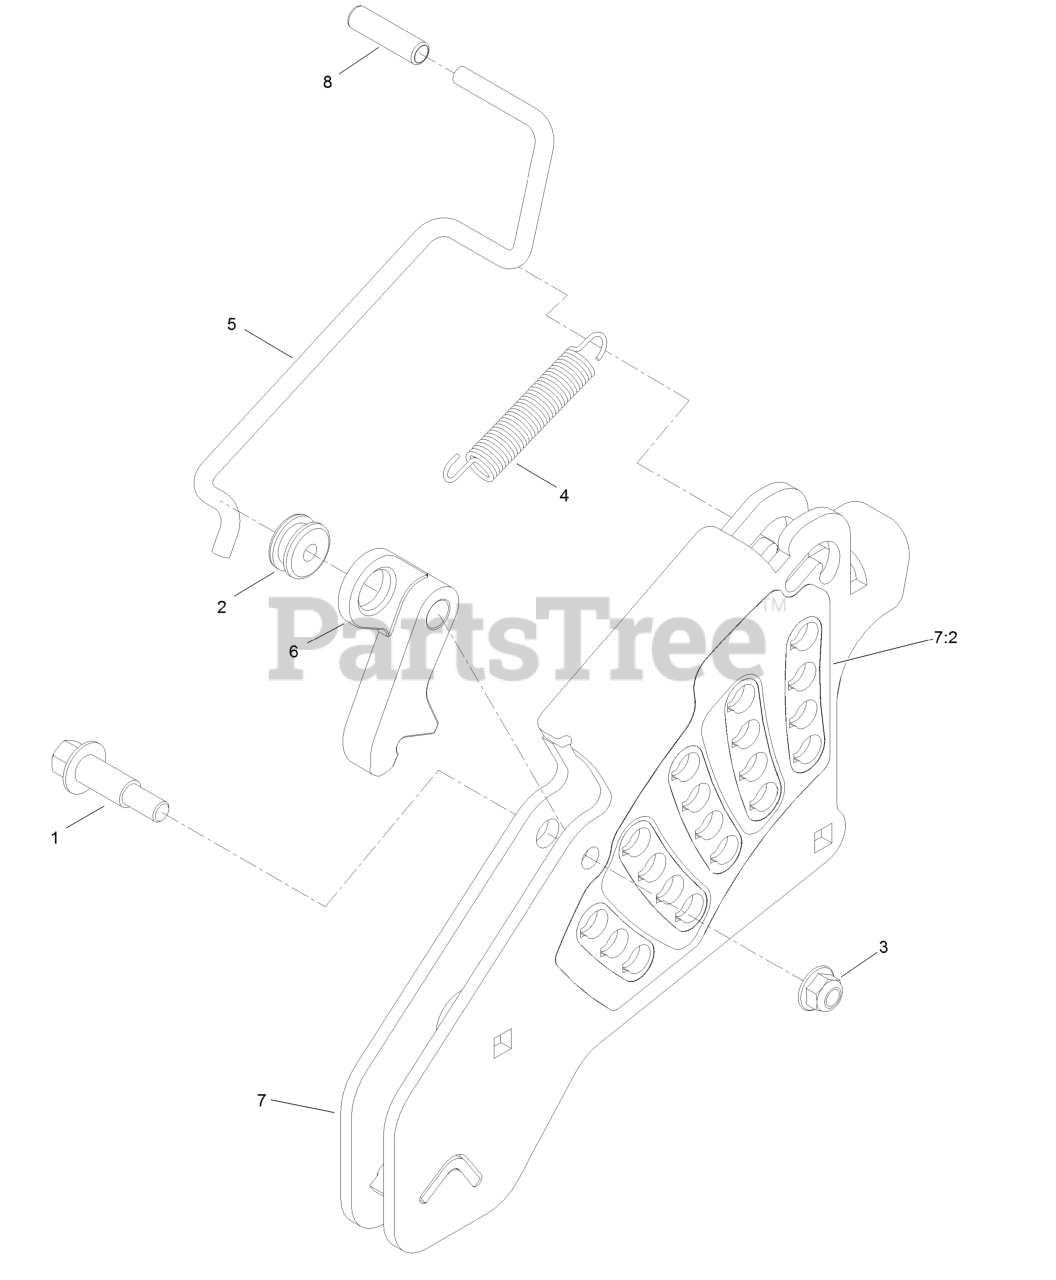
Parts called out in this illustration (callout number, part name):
1	Bolt-Shoulder
2	Grommet
3	Nut-HF, NI
4	Spring-Extension
5	Rod-Lock, Transport
6	Pawl-Transport, HOC
7	HOC Plate ASM
7:2	Decal-HOC
8	Grip-Lever
